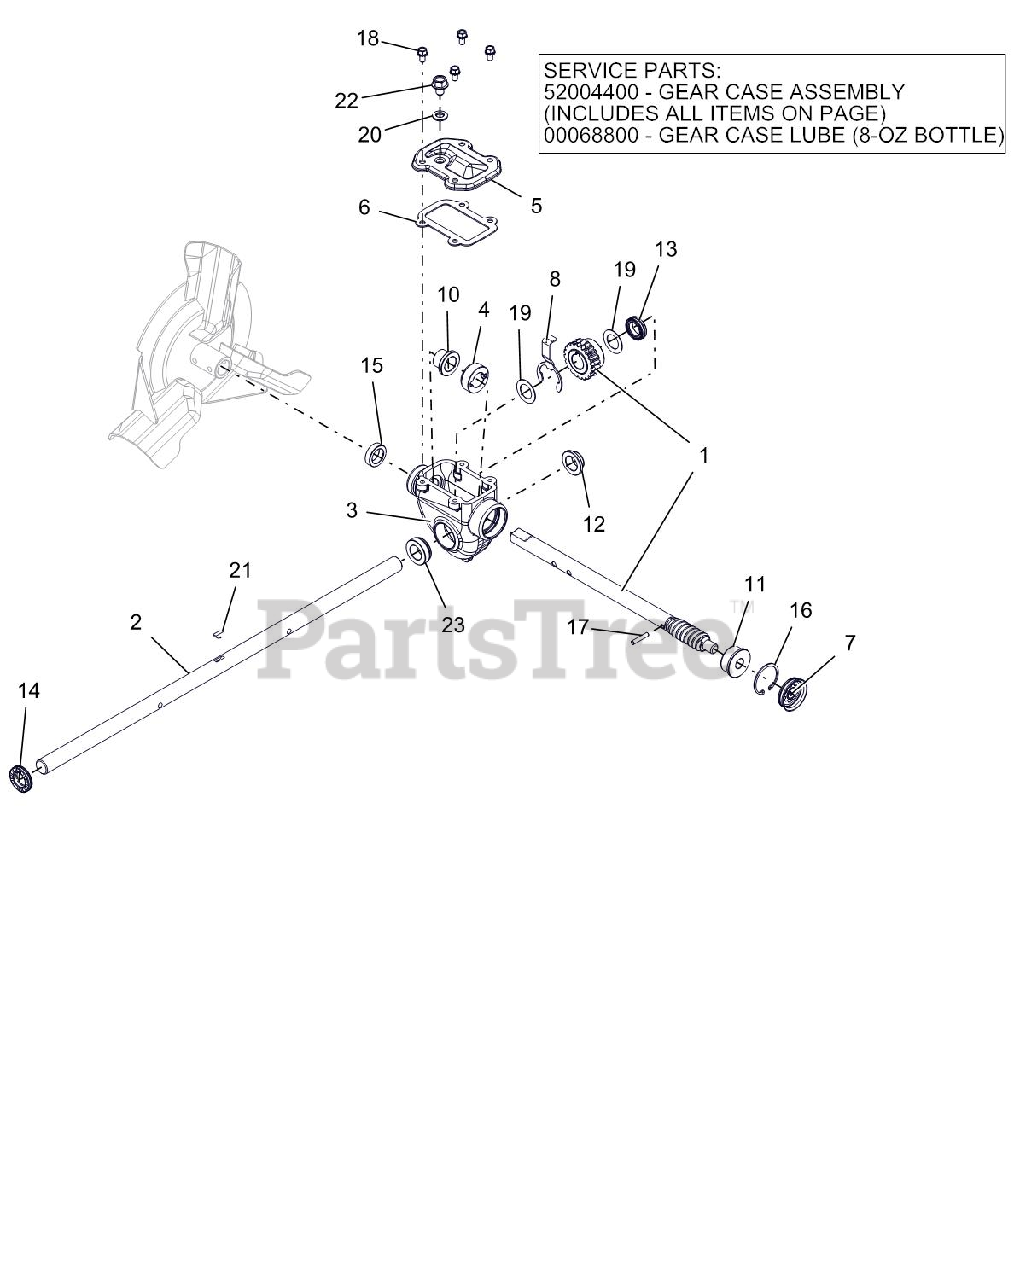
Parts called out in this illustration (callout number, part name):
1	SHAFT AND WORM GEAR ASSEMBLY
2	SHAFT, RAKE - 24" (.750 DIA)
3	GEARCASE, COMPACT MACHINED
4	THRUST COLLAR, .75" ID SLIPFIT
5	COVER, TOP - COMPACT
6	GASKET, TOP - COMPACT GEARCASE
7	COVER, GEAR CASE 1.50"
8	BUSHING RETAINER, COMPACT
10	BSHG-FLG .755X.878X.75X1.25
11	BSHG-FLG .503X1.303X.62X1.465
12	BSHG-FLG .755X.878X.424X1.25
13	SEAL-OIL .748X1.125X.312 TBC29
14	SEAL-OIL .748X1.300X.250 TBC29
15	SEAL-OIL .748X1.125X.312 TB2-H
16	RG-RTNG-INT 1.500X.050
17	PIN-STR .188X1.00 6150
18	BOLT, SEMS .25-20X.50 GR5 YWZC
19	WSHR-FL-STL .760X1.225X.032 YZ
20	WSHR-BND-SEAL .38X.75X.11 GALV
21	KEY-WDRF .19X.63 HRD #61
22	@SCR-ROLOK .38-16X.50 HWH YWZC
23	BSHG-FLG COMPACT, RIGHT
23	GEAR CASE, 24" IRON SM TOP-LD
24	ARIENS L3 LUBE, 8 OZ BOTTLE
